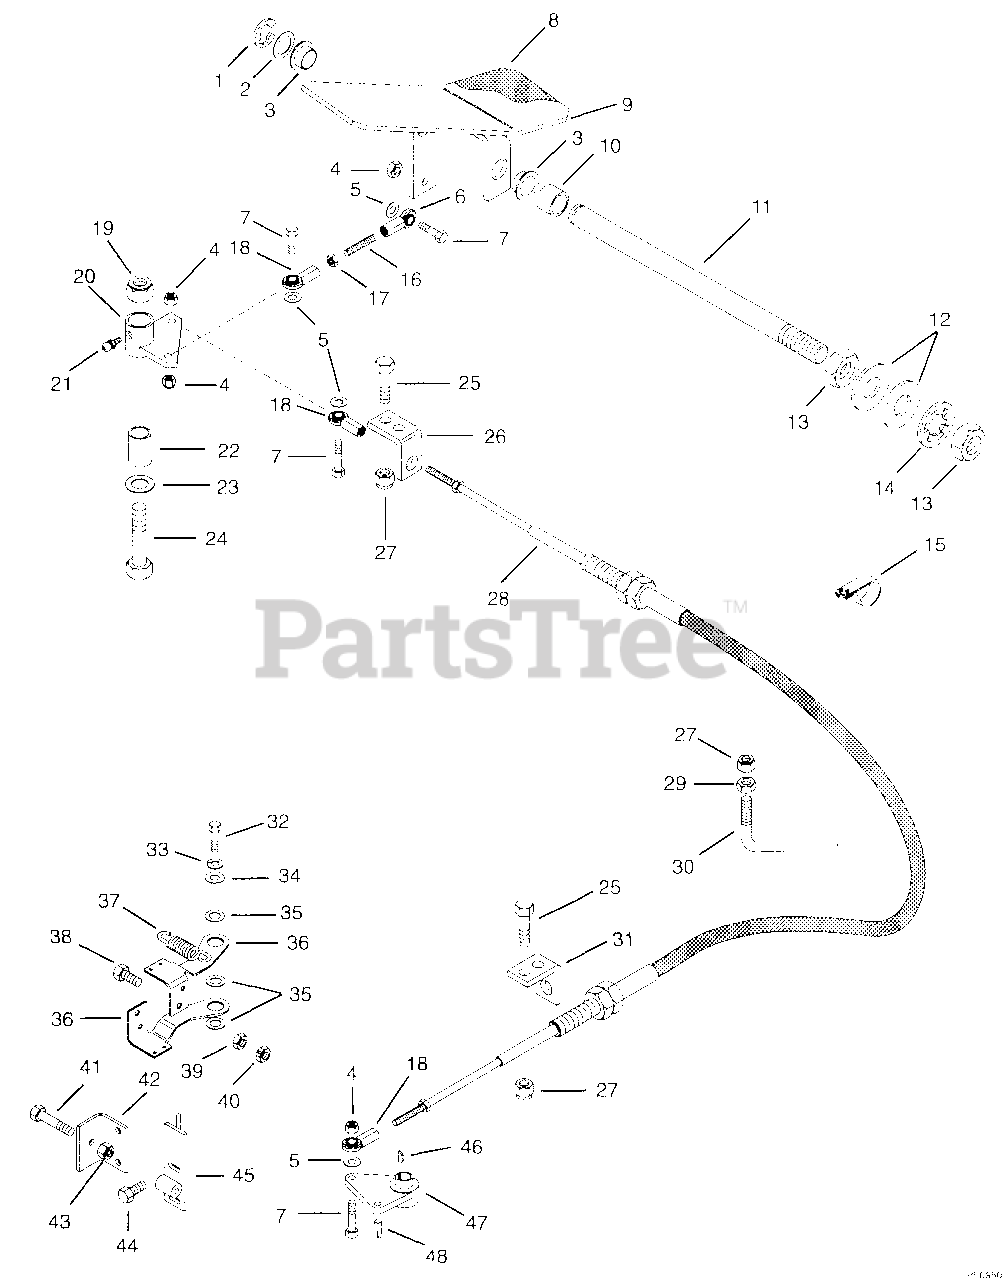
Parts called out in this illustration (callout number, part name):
1	Ring-Retaining-External .574 x .050
2	Bearing-Needle-Thrust .752 x 1.24 x .031
3	Bushing-Flange .762 x 1.0 x .580 x 1.48
4	Nut-Locking-Center .25-20
5	Washer-Flat-Steel .281 x .620 x .065
6	Rod End Left Hand
7	Bolt-Hex .31-18 x 1.75 Grade 5
8	Cover, Pedal
9	Weldment, Pedal
10	Bushing, Sleeve .782 x 1.00 x .710
11	Shaft, Pedal
12	Washer-Flat-Steel .812 x 1.50 x .139
13	Nut-Jam .75-16
14	Washer-Lock Internal .750
15	Clamp, Cushioned Steel
16	Rod
17	Nut-Jam .25-28
18	Rod End, Female 1/4-28
19	Nut-Locking-Center .50-13
20	Weldment, Lever
21	Fitting-Lube .25-28 x .256
22	Spacer, .562 x .855 x 1.56
23	Washer-Flat-Steel .50 x 1.25 x .083
24	Bolt-Hex .50-13 x 2.50 Grade 5
25	Bolt-Hex .38-16 x 1.00 Grade 5
26	Bracket, Cable
27	Nut-Locking-Center .38-16
28	Cable, Forward-Reverse
29	Nut-Jam .375-16
30	Rod, Cable Guide
31	Bracket, Cable
32	Bolt-Hex .25-20 x 1.50 Grade 5
33	Washer-Locking .25 x .062
34	Washer-Flat-Steel .281 x 1.250 x .048
35	Washer-Flat-Steel .760 x 1.125 x .030
36	Lever, Neutral
37	Spring-Tension .075 x .75 x 2.25
38	Bolt-Hex .31-24 x .75 Grade 5
39	Nut-Jam .312-24
40	Nut-Locking-Center .312-24
41	Bolt-Hex .31-18 x 1.25
42	Bracket
43	Nut-Locking-Nylon .312-18
44	Screw-Tapping .31-18 x .88 HWH
45	Weldment, Neutral Stop
46	Key, Woodruff .13 x .50
47	Arm, Transmission Control
48	Pin-Groove .250 x .75
